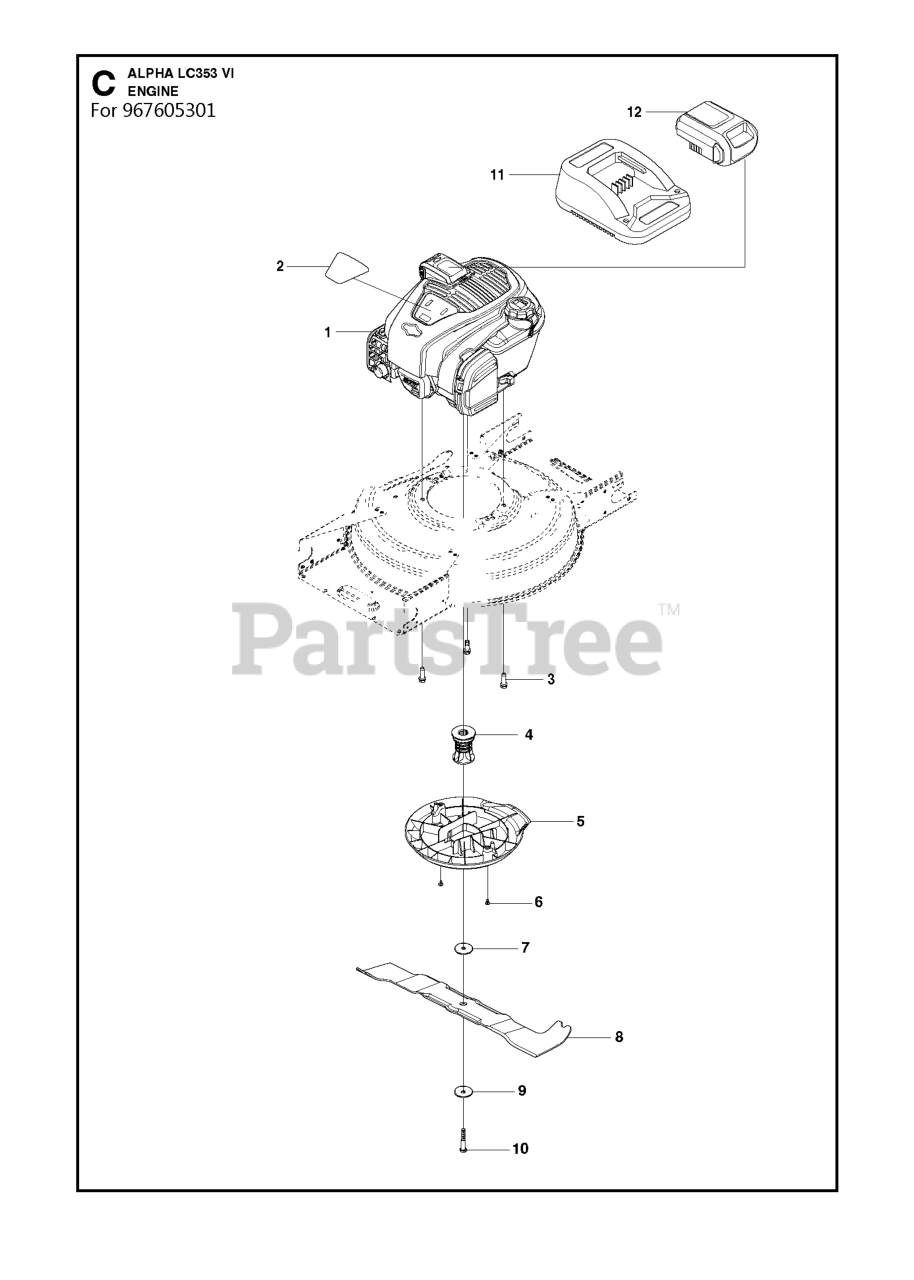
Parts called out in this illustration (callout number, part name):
1	Husqvarna TBD
3	BOLT 3/8-16X1-1/8
5	BELT COVER A009-2
6	SCREW ITXPANTT M5X10 ZPB (A00
